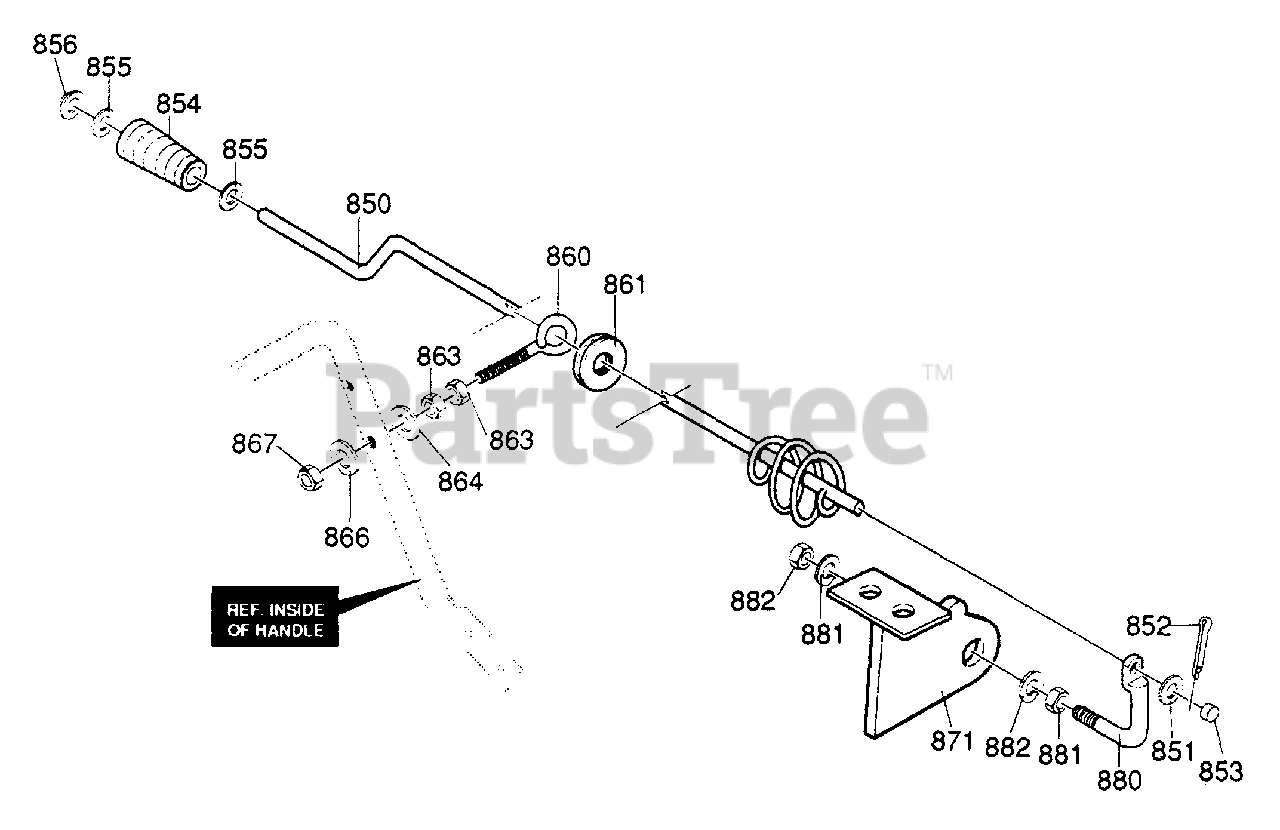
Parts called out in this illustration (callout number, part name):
850	CRANK, ASSY CHUTE
851	FLATWASHER,.406x.81 x.065
852	PIN, COTTER.094 DIAx1.00 LONG
853	CAP, PLASTIC, 3/8 ID
854	KNOB, SLEEVE
855	FLATWASHER, .406x.81 x.065
856	NUT, PUSH ON 3/8"
860	BOLT, EYE 3/8-16x5.00 .63ID
861	GROMMET, EYE BOLT. 40IDx.435WD
863	NUT, 3/8-16 HEXJAM
864	FLATWASHER, .406x.81x.065
866	FLATWASHER, .406x.81 x.065
867	NUT, 3/8-16 HEXNYL
871	PLATE, ASSY MTG STL CHUTE
880	ROD, CHUTE CONT 420T
881	NUT, 1/2-20 HXJAM
882	WASHER, REGSPTLK.523x.87x.14
